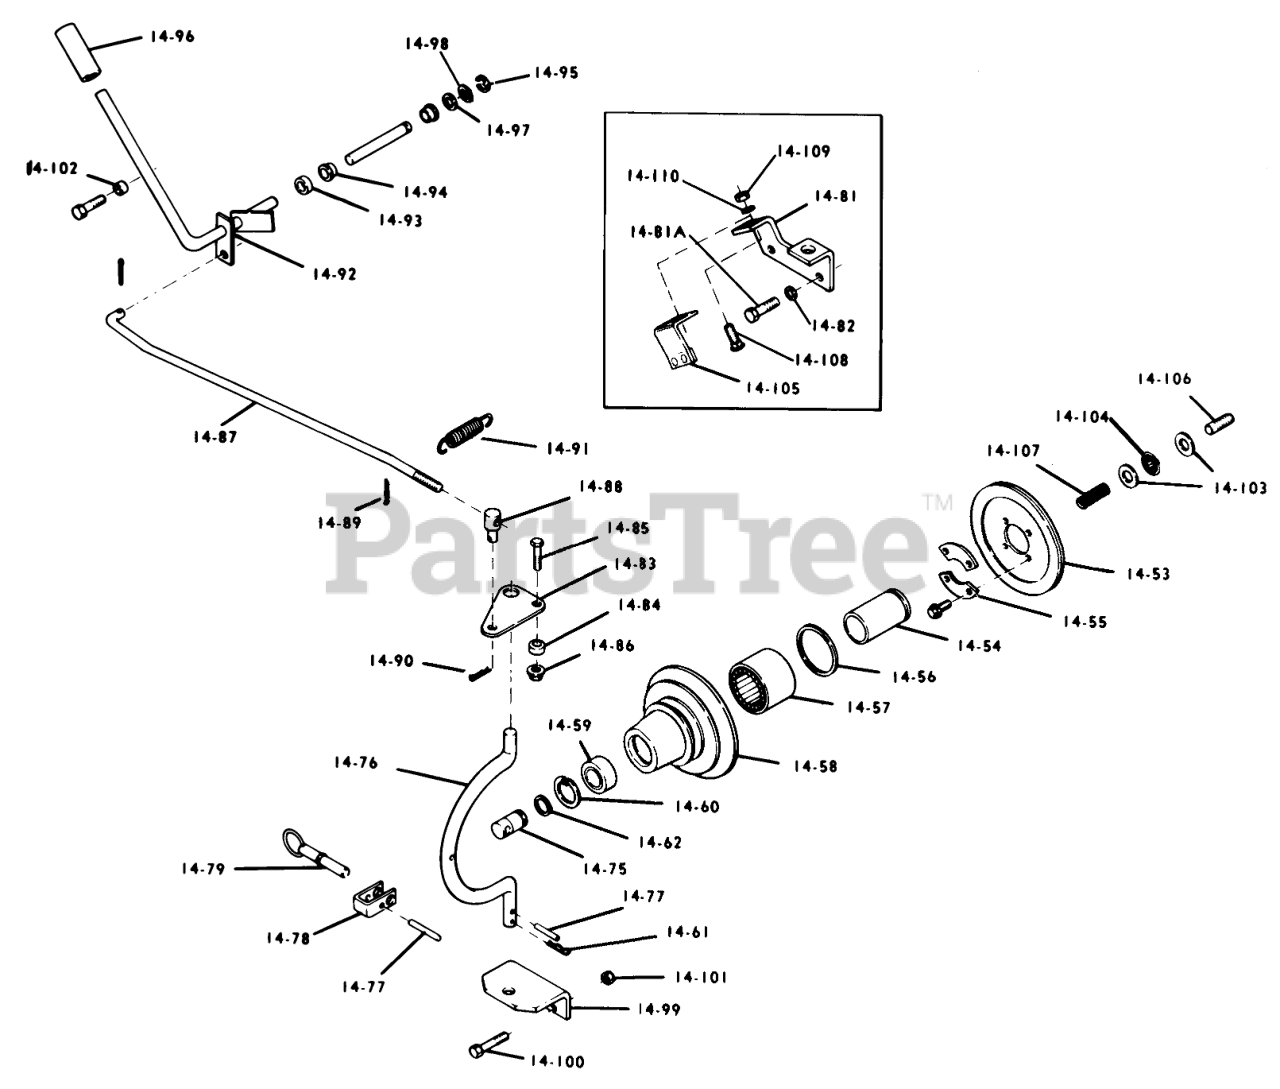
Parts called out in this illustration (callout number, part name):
14-53	Clutch Plate & Facing
14-53	Clutch Plate
14-53	Facing
14-53	RIVET-BRASS
14-54	RACE-BEARING
14-54	BEARING RACE
14-55	RETAINER
14-55	Screw
14-56	SEAL-OIL
14-57	Seal
14-58	Housing-Clutch
14-59	Bearing
14-60	Ring-Snap
14-61	Hairpin
14-62	RING-SNAP, EXTERNAL
14-75	SHAFT-PTO
14-76	ROD HOUSING (NS)
14-77	PIN-SPIROL
14-78	Clevis
14-79	Pin
14-81	BRACKET
14-81	BRACKET-ENGINE B
14-81A	H H C S
14-81A	Bolt
14-82	LOCKWASHER
14-83	PLATE R
14-84	SPACER
14-85	BOLT
14-86	LOCKNUT-FLANGE
14-87	Clutch Rod
14-88	TRUNNION
14-89	Pop Rivet
14-90	Hairpin Cotter
14-91	Spring
14-92	Plug, Drain
14-93	SPACER
14-94	BUSHING-FLANGED
14-95	E Ring
14-96	GRIP
14-97	Washer
14-98	SHIM-WASHER
14-99	Axle
14-100	Bolt
14-101	Nut
14-102	Spacer
14-103	RACE THRUST
14-104	THRUST BEARING
14-105	PTO Plate
14-106	STUD 7/16
14-107	SPRING
14-107	SPRING-COMPRESSION
14-108	Bolt-Carriage
14-109	Nut
